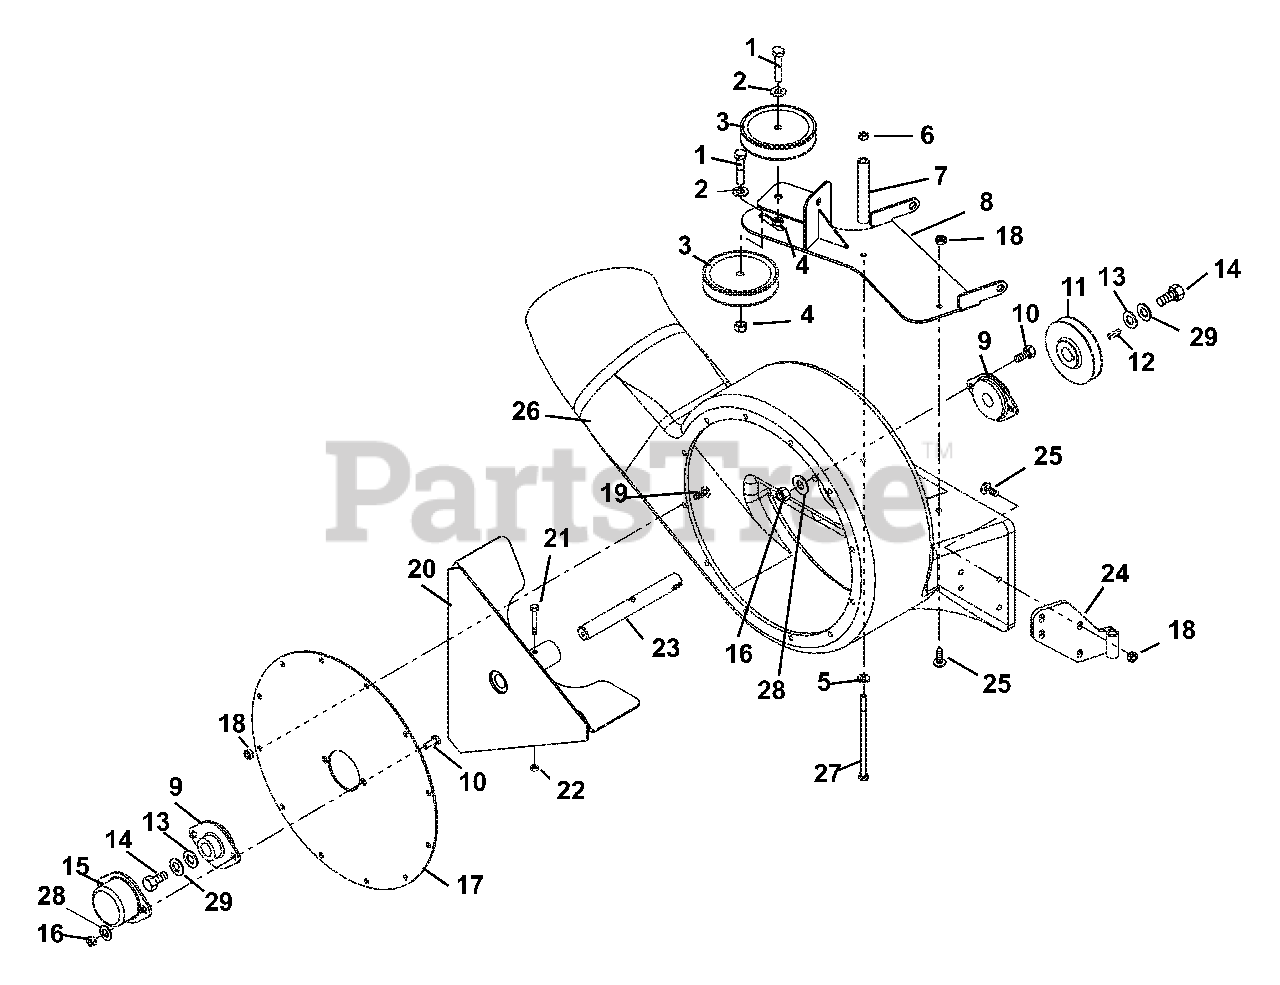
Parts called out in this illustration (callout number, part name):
1	Bolt-Hex .38-16 x 1.50 Grade 5
2	Washer-Flat-Steel .38 x .875 x.083
3	Idler-V 3.00 x .38
4	Nut-Locking-Flange .38-16
5	Washer-Flat-Steel .281 x .62 x.065
6	Nut-Locking-Center .25-20
7	Spacer-.334 I.D. x .500 O.D. x 4.625
8	Bracket-Complete Mule Assembly
9	Bearing, 2 Bolt Flange-.75 ID
10	Bolt-Hex .31-18 x 1.00 Grade 5
11	Pulley, Driven 3.50
12	Key-Square .187 x .50 x .187
13	Washer-.328 x 1.0 x .094
14	Bolt-Hex .25-28 x .75 Grade 5
15	Cover-Bearing
16	Nut-Locking-Nylon .312-18
17	Plate-Bearing Mount
18	Nut-Locking-Flange .250-20
19	Screw-Machine .250-20 x .50
20	Impeller-Grass Pump
21	Bolt-Hex .25-20 x 1.50 Grade 5
22	Nut-Locking-Center .25-20
23	Shaft, Grass Pump
24	Weldment, Mounting Bracket
25	Screw-Machine .25-20 x .75
26	Housing-Grass Pump
27	Bolt-Hex .25-20 x 6.00 Grade 5
28	Washer-Flat-Steel .312 x .734 x.065
29	Washer-Lock .25 x .062
